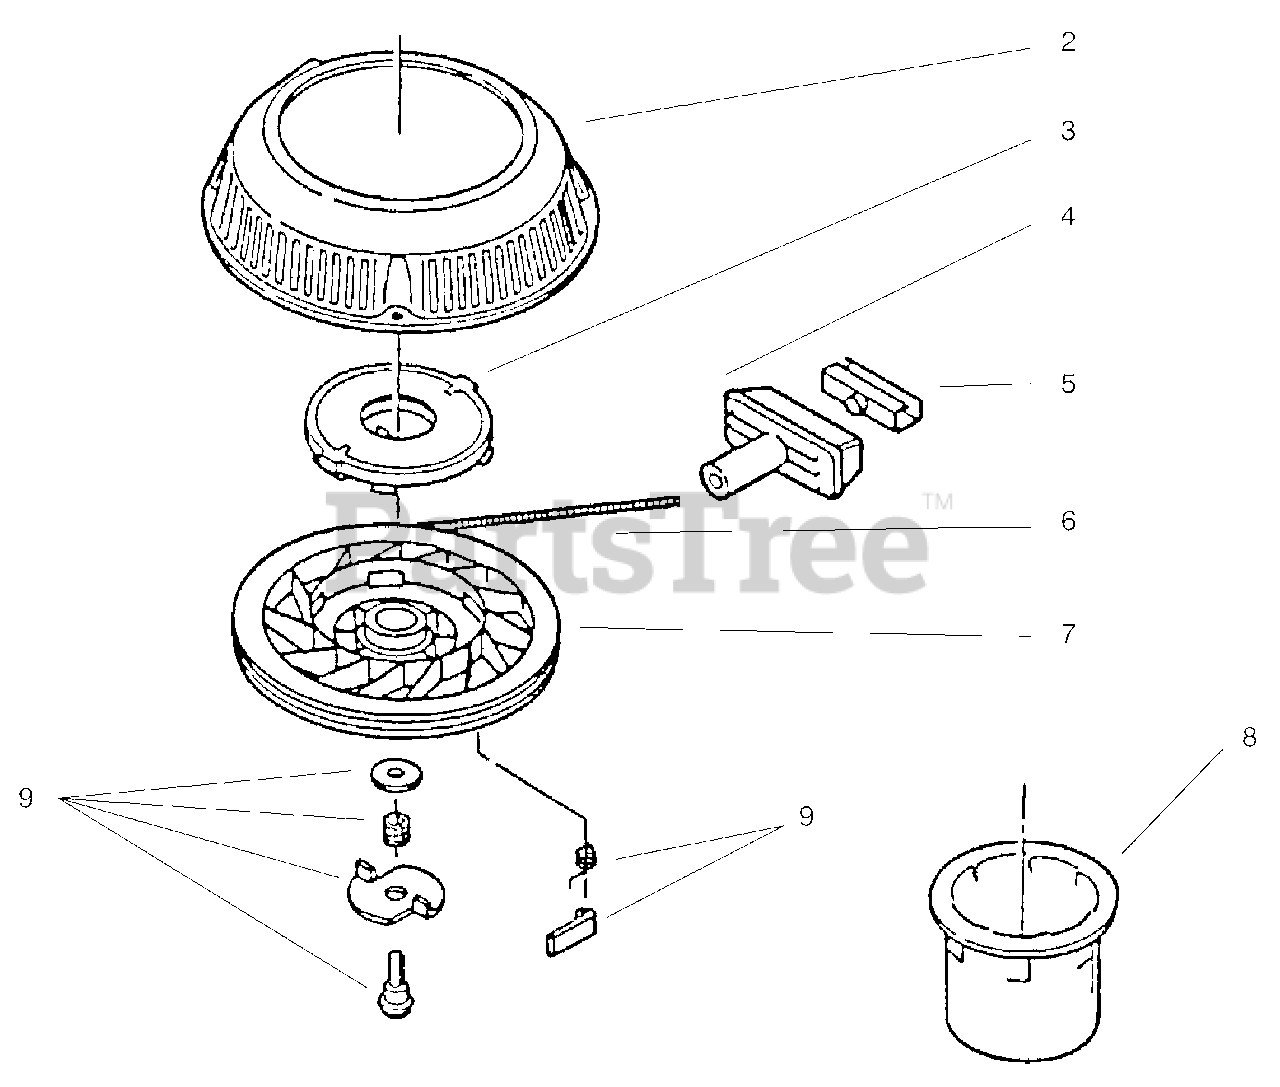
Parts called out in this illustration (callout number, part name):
2	Starter Housing & Shaft
3	Spring & Keeper
4	Handle-Starter
5	Clip-Rope
6	Rope
8	Hub-Starter
9	Kit-Dog
